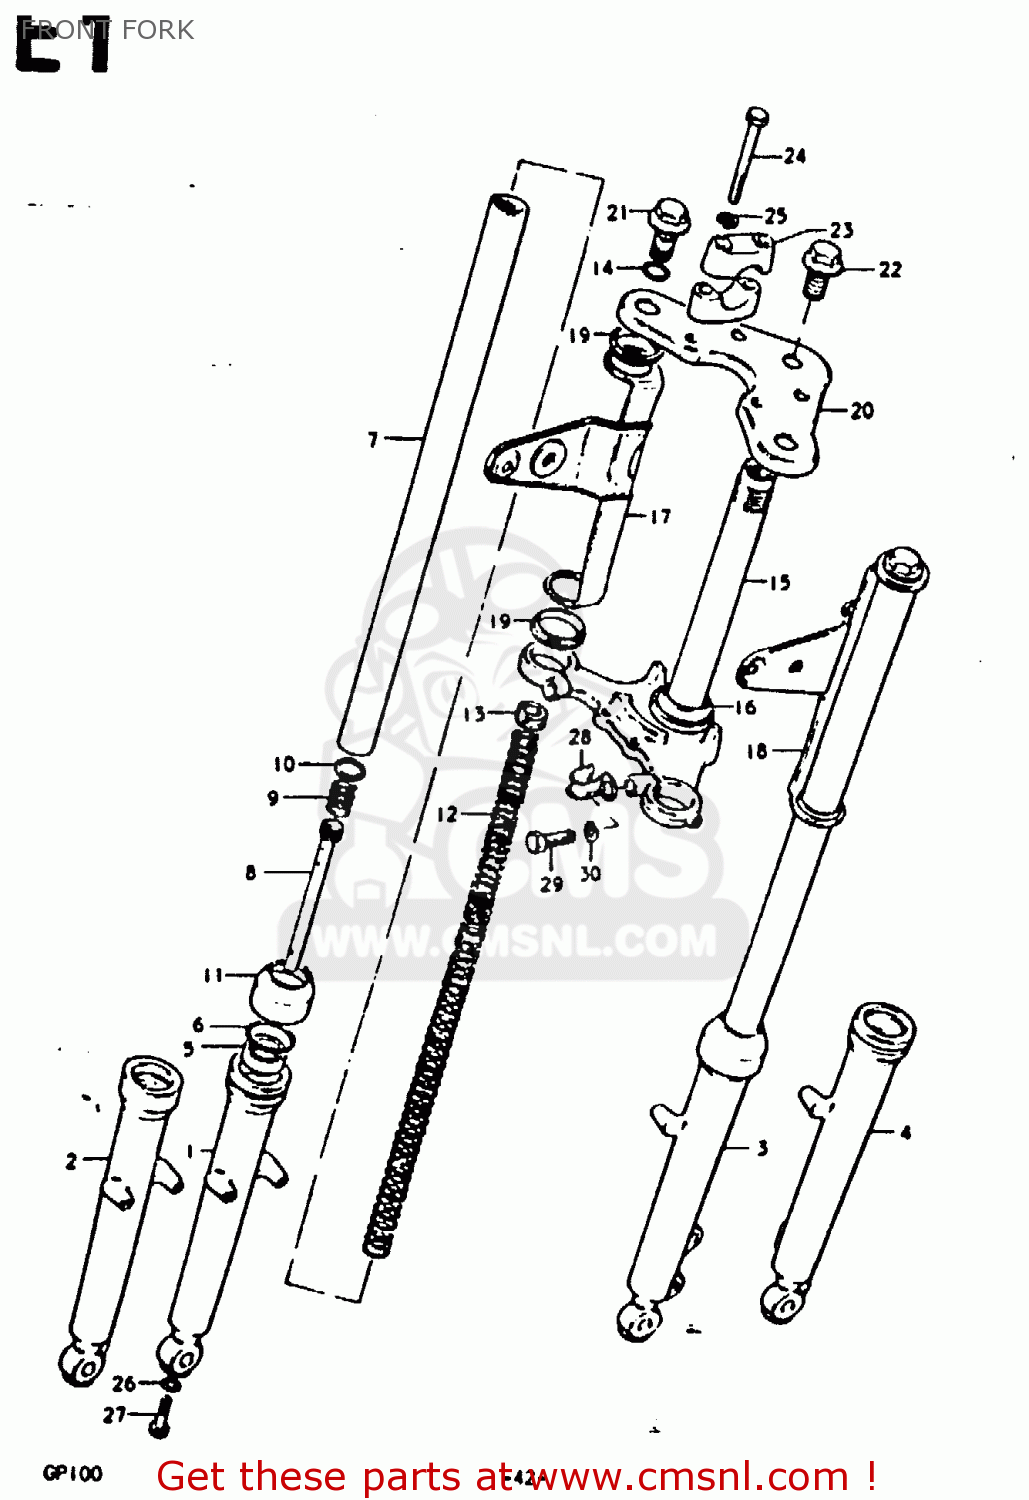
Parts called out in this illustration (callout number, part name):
2	OUTER TUBE, RH
4	OUTER TUBE, LH
5	SEAL,OIL
6	RING,SNAP
7	TUBE, INNER
8	CYLINDER
9	SPRING
10	RING
11	DUST SEAL
12	SPRING
13	NUT
14	O-RING,FORK INNER TUBE
15	STEM, STEERING
16	RACE,STEERING OUTER LWR
17	BRACKET, HEADLAMP RH (BLACK)
18	BRACKET, HEADLAMP LH (BLACK)
19	GASKET (NAS)
20	HEAD, STEERING STEM (BLACK)
21	CAP
22	BOLT
23	HOLDER,HANDLE(BLACK)
24	BOLT 8X55
25	LOCK WASHER
26	GASKET (NAS)
27	BOLT,FORK CYLINDER(10X25)
28	CLIP,SPEEDOMETER CABLE
29	BOLT 10X30
30	LOCK WASHER
